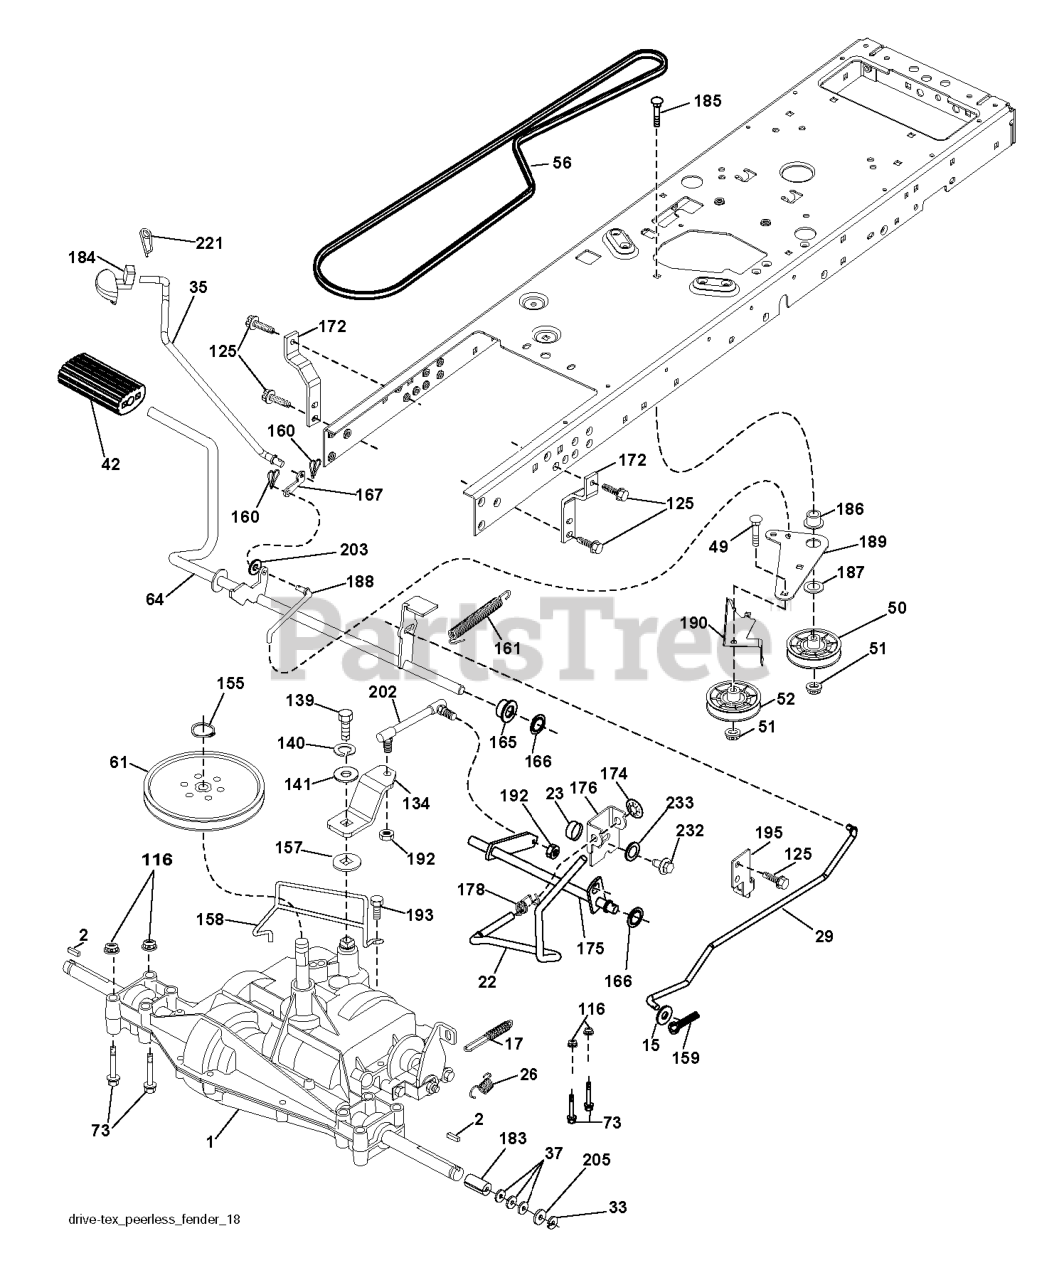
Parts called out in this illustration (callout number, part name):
2	SQUARE KEY
15	WASHER
17	SPRING.BRAKE.PEERLESS.TEX
22	ROD.SHIFT.FENDER.TLT.2006
23	KNOB.DUCKHEAD.1/2
26	SPRING.BRAKE.RTN.GR.DR
29	ROD.BRAKE.PEERLESS
35	ROD.CNTRL.PARK.PREDATOR.LT.TEX
42	PEDAL COVER T
50	IDLER.FLAT.910.OFFSET
51	NUT LOCK FLG 3/8-16 UNC
52	IDLER.V-GROOVE.910.OFFSET
56	V-BELT.TRACTOR.DRIVE.P
61	PULLEY TRANS
64	SHAFT.ASM.PEDAL.BRAKE.
73	BOLT HEX 5/16-18 GR 5
116	NUT LOCK HEX FLANGE 5/16-18
125	SCREW
139	BOLT 1/4-28X3/4
140	LOCKWASHER
155	RETAINING RING LT
157	WASH-SHFT PLT LT
158	KEEPER.PMS.18/20.D4365
159	COTTER PIN
160	RETAINER CLIP
161	SPRING, RETURN LT
165	BUSHING.SHAFT.BRAKE.HAND
166	NUT.PUSH.625.2006
167	LATCH.BRAKE.SPRING
172	STRAP.TRQ.LH.GEAR.DRIV
174	NUT.PUSH.500.2006
175	SHAFT ASM SHIFT
176	ARM.CLEVIS.ROD.SHIFT
178	SPRING.SHIFT.GT2006
183	SPACER AXLE
184	HANDLE PARKING BRAKE
186	SPACER.RETAINER
187	WASHER 12/32X2X10GA
188	RP.LINK.CLUTCH.GROUND.DRIVE
189	BELLCRANK.GROUND.DRIVE.TEX.
190	KEEPER.BELLCRANK.DRIVE
192	NUT LOCK CENTER 1/4 -28 FNTHD
193	SCREW 5/16"
195	BRKT.ROD.BRAKE.PEERLES
202	LINK.SHIFT.PMST.18" (SPG1286)
203	WASHER
221	RETAINER.SPRING.CLIP.H
232	BOLT FIN HEX 7/16-14 X 1
233	WASHER SERRATED
